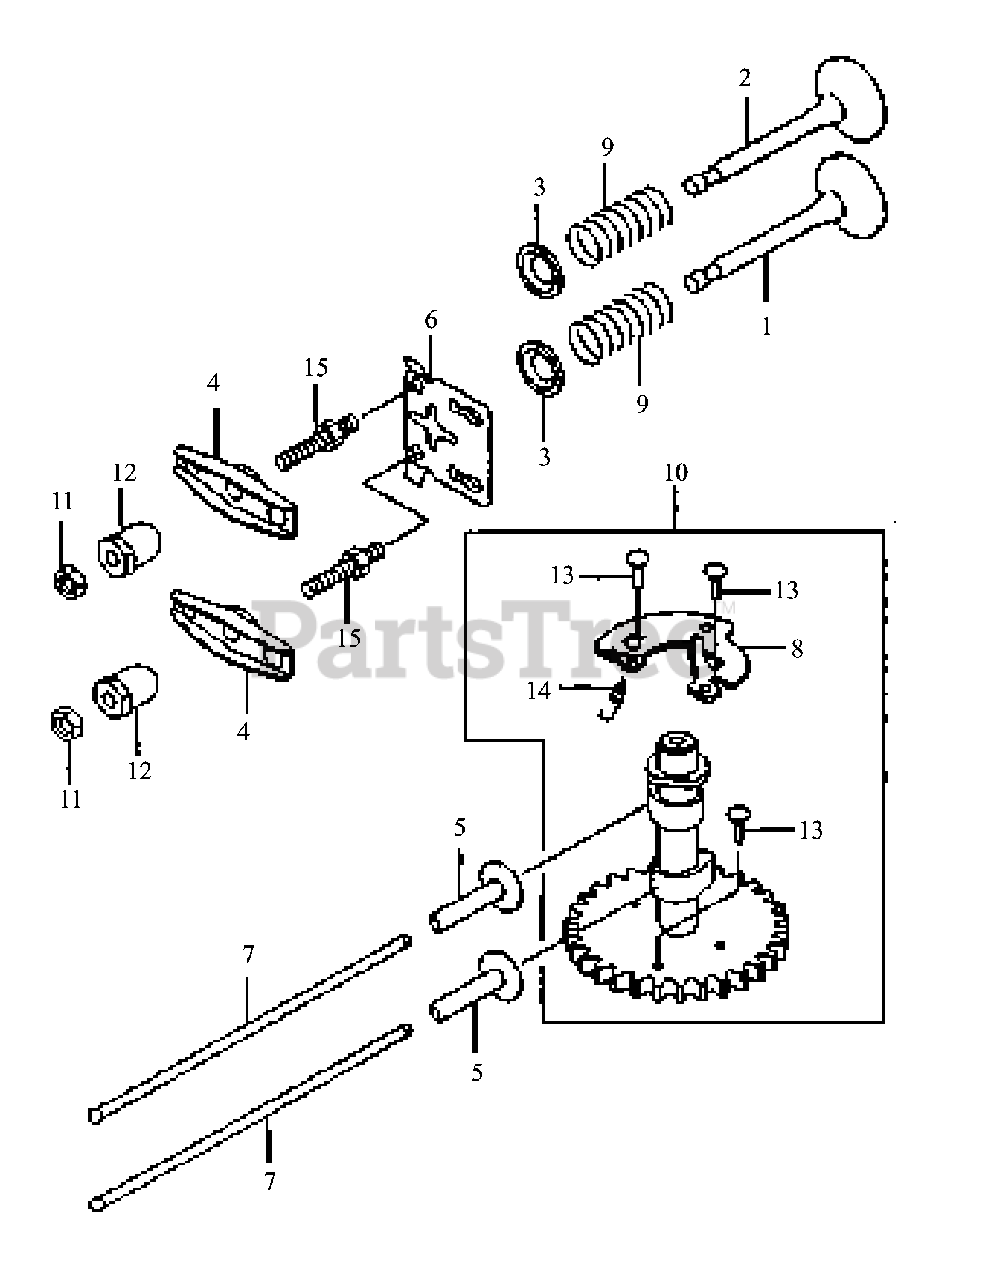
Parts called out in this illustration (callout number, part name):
1	Valve, Intake
2	Valve, Exhaust
3	Retainer, Valve Spring
5	Tappet
8	Decompressor
9	Spring, Engine Valve
10	Camshaft
14	Spring
